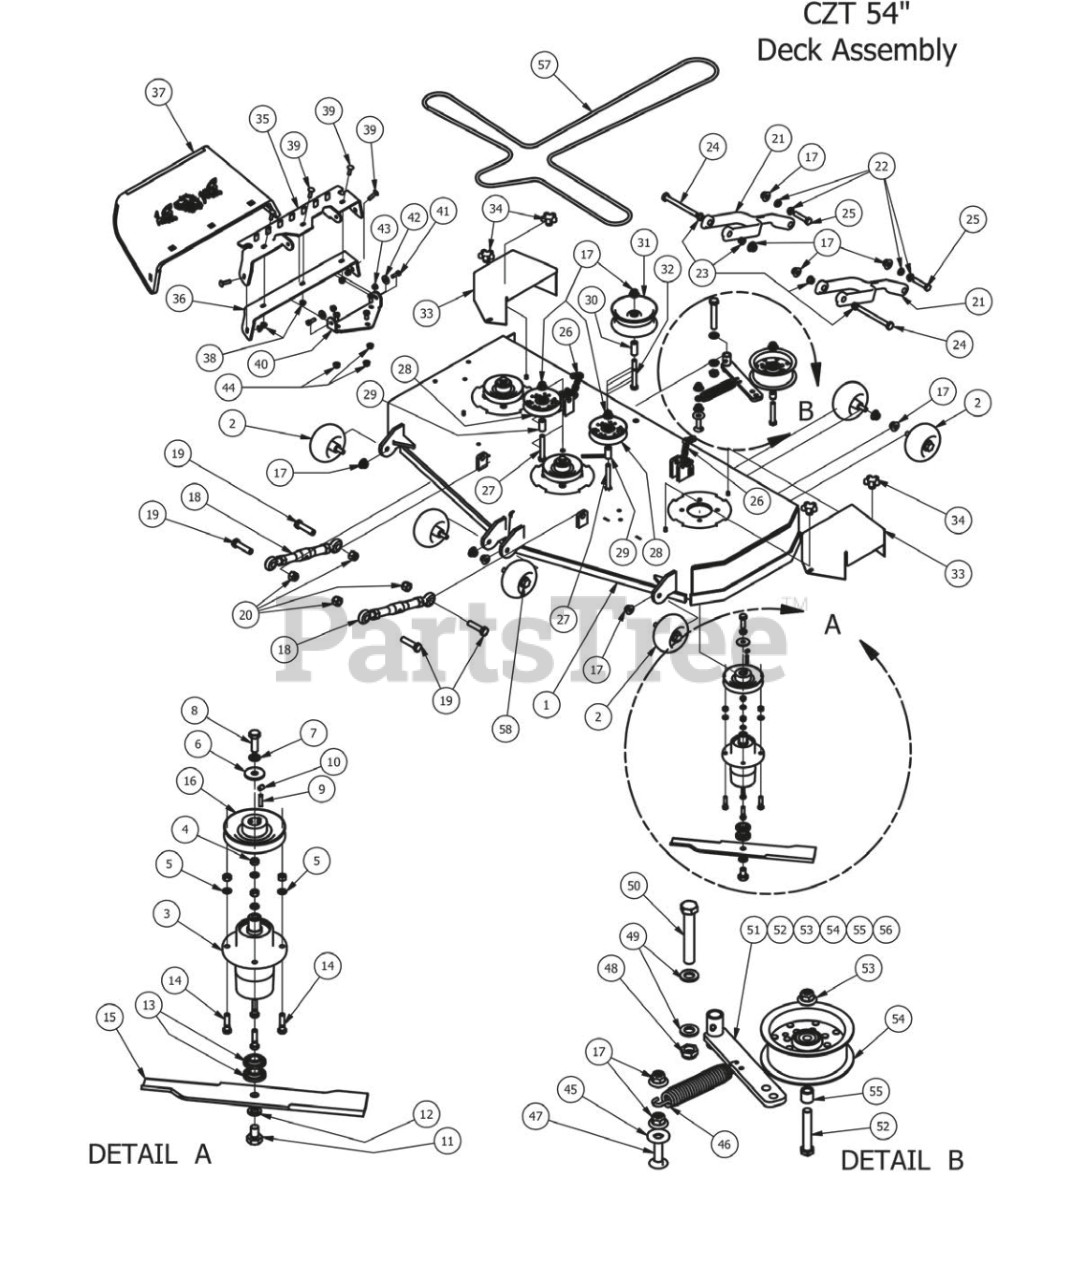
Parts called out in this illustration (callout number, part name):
1	2013 cZT 54" Deck
2	Deck Wheel
3	Short Shaft Spindle
4	3/8" Hex Nut
5	3/8" Lock Washer
6	1/2 Belleville Washer
7	1/2" Lock Washer
8	1/2"-20 x 1 1/2 Grade 5 Fine Thread Bolt
9	1/4" x 1" Key
10	5/16 Set Screw
11	5/8" x 1 1/2" Grade 8 Bolt
12	5/8" Lock Washer
13	Spindle Bearing
14	3/8" x 1 1/2" Hex Bolt
15	54" Deck Fusion Blade For Outlaw
16	5" Deck Pulley
17	1/2-13 Nylon Flange Nut-Orange
18	Turnbuckle (Top Link)
19	5/8" x 2 1/2" Hex Bolt
20	5/8 Std NC Nylock Nut
21	Deck Arm Assembly
22	Flange for Lower Deck Arm
23	Flange Bushing For Deck Arm upper
24	1/2" x 5 1/2" Bolt
25	1/2-13X 2-1/4 GR Hex Bolts
26	Chain assembly
27	1/2 x 3 1/2 Flange Bolt Grade 8
28	4-3/4 Idler Pulley
29	.502 ID X.75 OD X 1.500 Leng
30	1 3/4" Pulley Spacer
31	5 3/4" Deck Idler Pulley
32	1/2" x 4" Bolt (Grade 8)
33	Pulley Cover
34	5/16" Knob
35	Upper Hanger
36	Discharge Lower Chute Bracket
37	Rubber Discharge Chute
38	5/16" Nylon Flange Nut
39	5/16" x 1 1/4" Carriage Bolt
40	Discharge Chute Hanger (deck mounted)
41	5/16" x 1" Bolt
42	.360 ID Plastic Washer
43	5/16" Nylon Flange Nut
44	3/8" Flange Nut
45	1/2" Flat Washer
46	2009 Deck/Pump Idler Spring
47	1/2 x 2" Carriage Bolt
48	5/8" Nylock (1/2 Jam)
49	.635 ID Plastic Washer
50	5/8" x 4" Hex Bolt
51	Deck Idler
52	1/2-13 x GR 5 Hex Bolt Zinc
53	1/2-13 Nylon Flange Nut-Orange
54	5 3/4 flat idler-32fI-92-008
55	3/4 OD X 1/2 ID x 3\4 Length
56	Deck Idler Assembly (Components 51,52,53,54,55,)
57	B155.75 Belt
58	Deck Wheel Bolt
